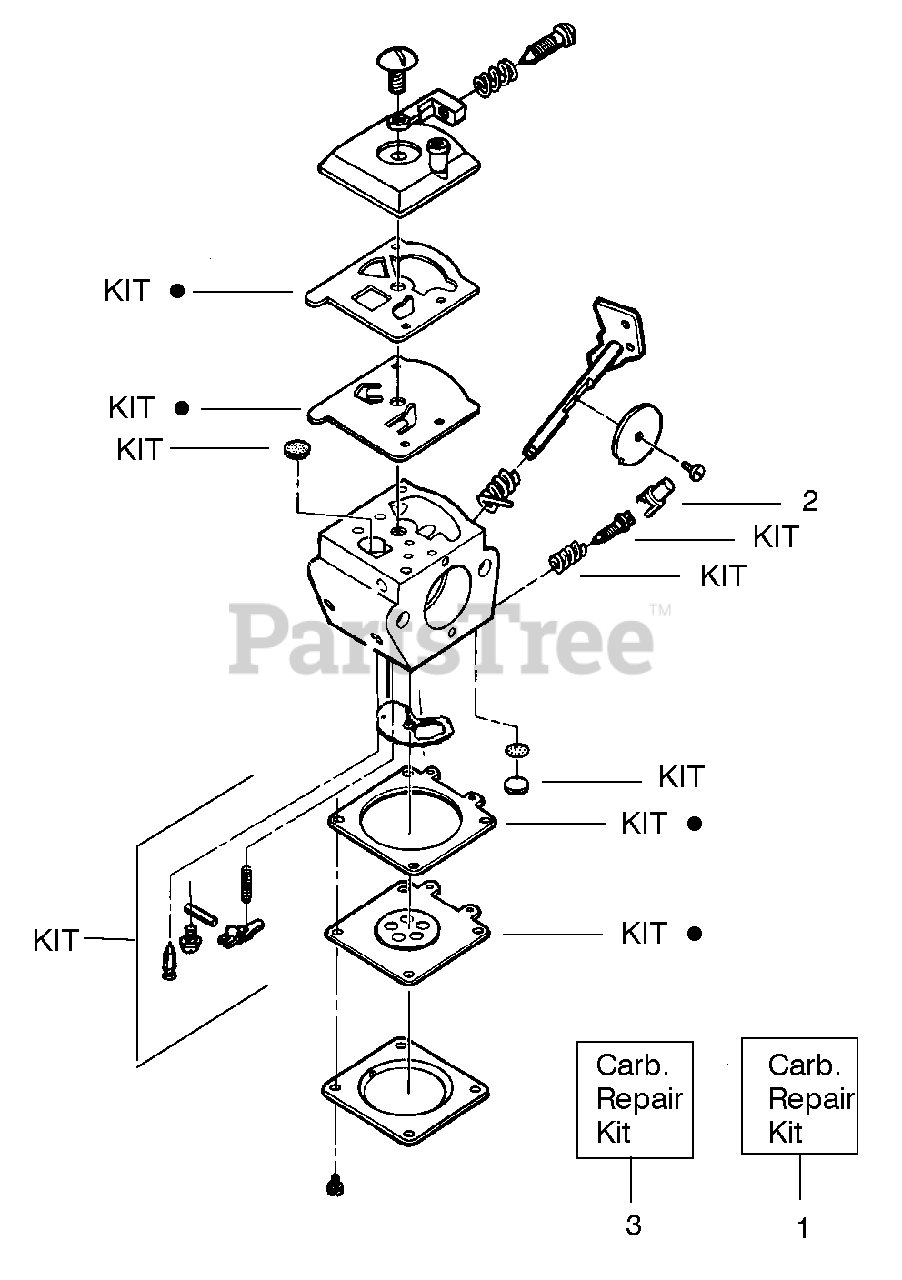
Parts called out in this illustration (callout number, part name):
1	Carburetor Repair Kit
2	Limiter Cap
3	Gasket/Diaphragm Kit
